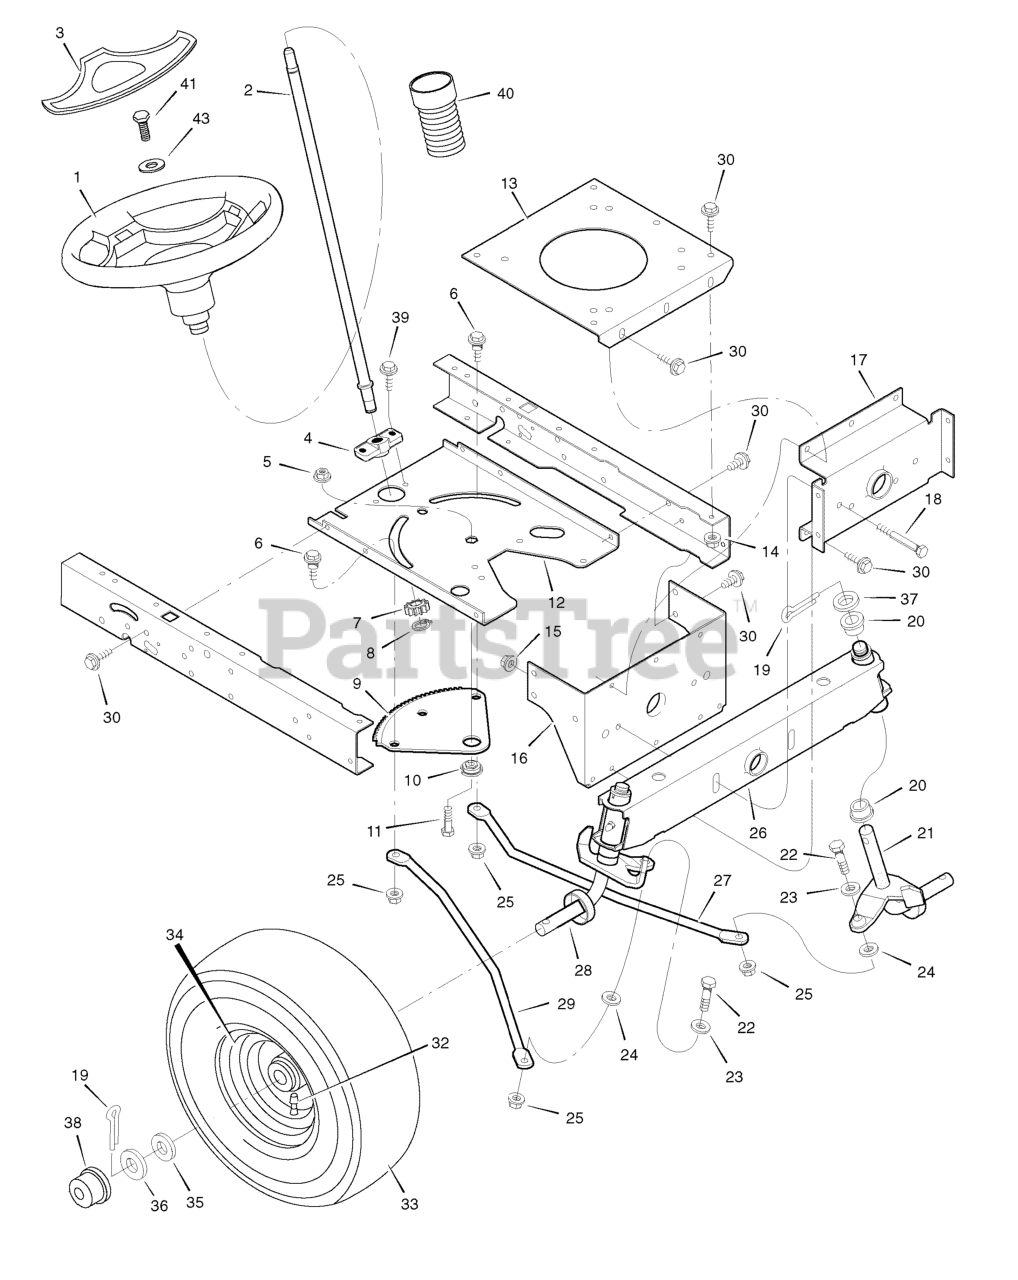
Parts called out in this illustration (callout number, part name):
1	WHEEL, Steering
2	POST, Steering
3	COVER, Steering Wheel
4	Bearing
5	Nut, Flange **
6	BOLT, Shoulder
7	GEAR, Pinion **
8	Ring, Snap **
9	GEAR, Sector
10	BEARING
11	BOLT
12	PLATE, Steering
13	PLATE, Engine
14	NUT, Flange
15	NUT, Flange
16	BRACKET, Hanger
17	AXLE, Hanger
19	PIN, Cotter
20	BEARING
21	SPINDLE ASSEMBLY, Left
22	BOLT
24	WASHER
25	NUT, Flange
26	AXLE ASSEMBLY
27	DRAG LINK, Left
28	SPINDLE ASSEMBLY, Right
29	DRAG LINK, Right
32	STEM, Valve
34	WHEEL & TIRE ASSEMBLY
38	HUB CAP
40	BELLOWS
41	SCREW, Hex
43	WASHER
